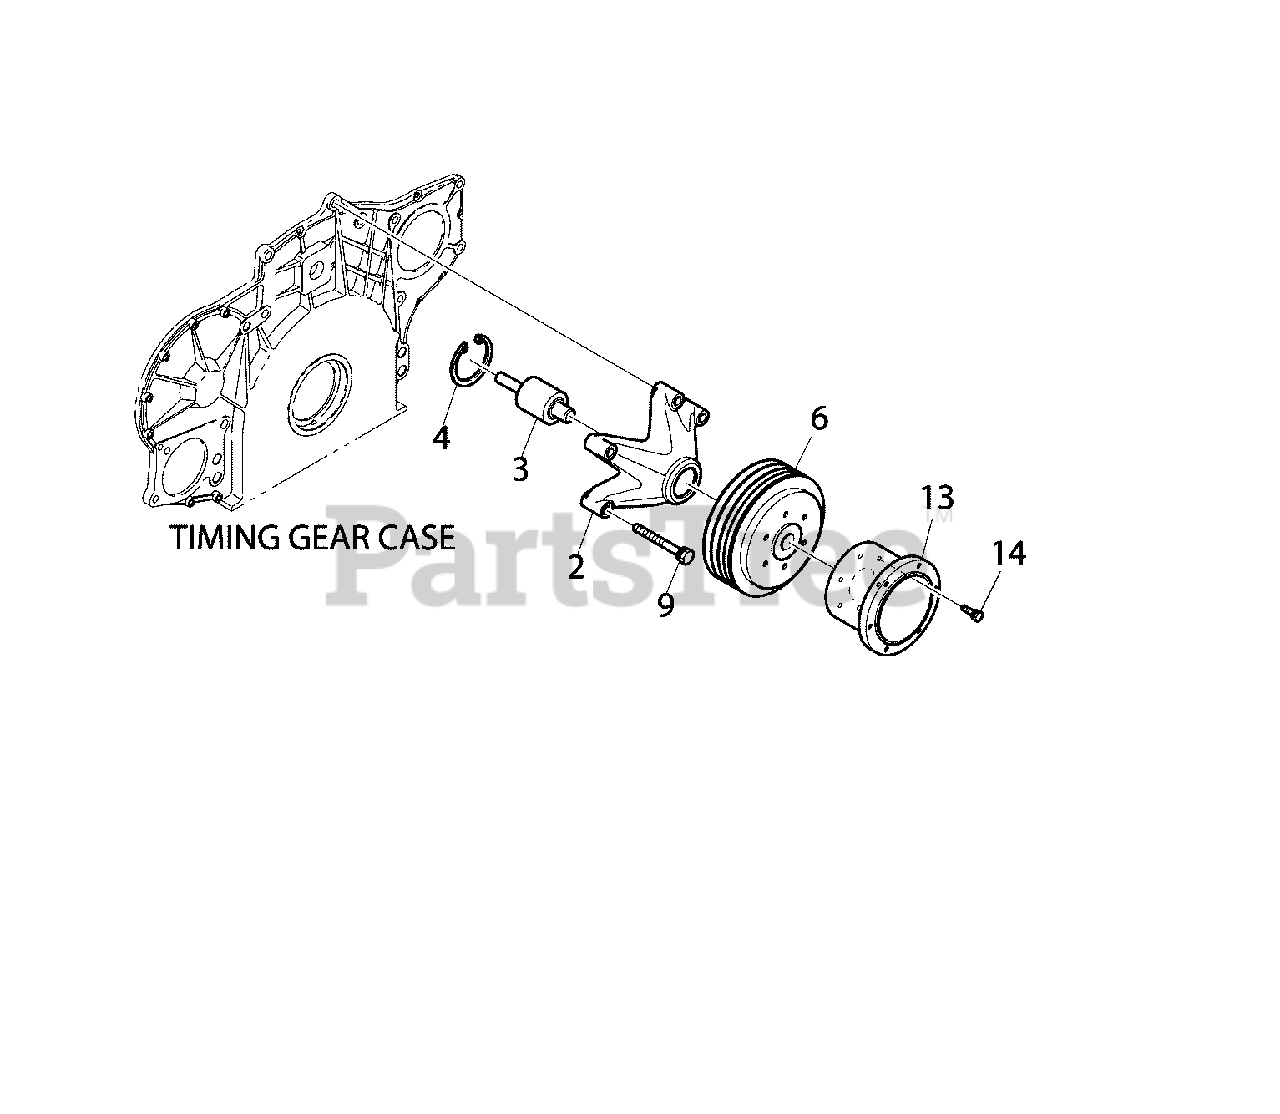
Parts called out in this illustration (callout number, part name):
1	* MOUNTING, FAN
2	* MOUNTING, FAN
3	* BEARING, BALL
4	* RING, SNAP
6	* PULLEY, FAN
9	* BOLT
13	* FLANGE, FAN
14	* BOLT
